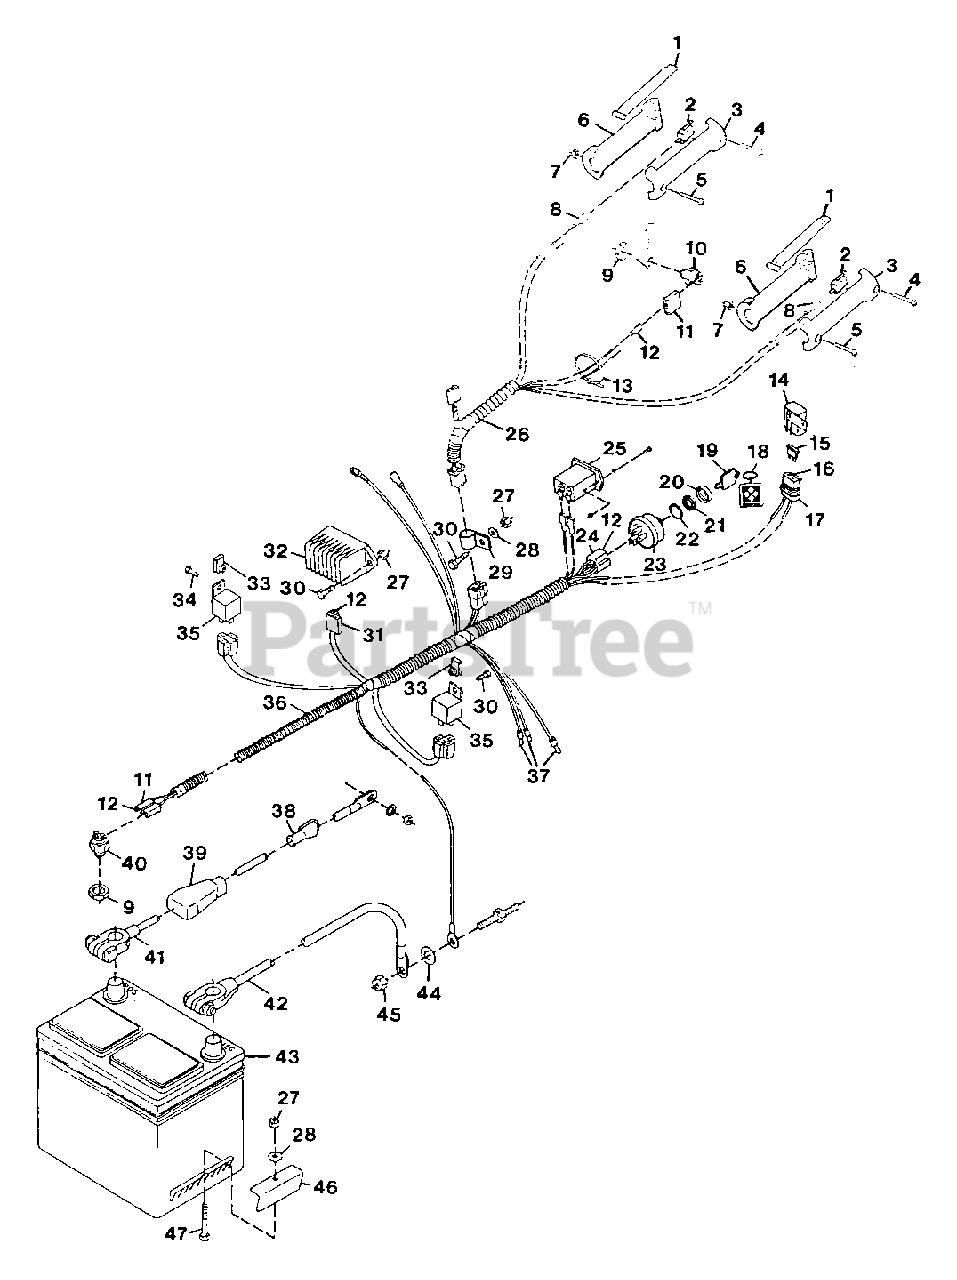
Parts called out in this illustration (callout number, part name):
1	Lever
2	Switch
3	Handle, L.H.
4	Screw, Machine 10-24x.625 PHD
5	Screw, Machine 10-24x1.50 PHD
6	Handle, R.H.
7	Nut, Lock 10-24
8	Terminal, Female
9	Nut, Stamped 9/16-18
10	Switch, Neutral Start
11	Connector, 2-Wire Switch
12	Terminal
13	Tie Wrap, Black
14	Cover
15	Fuse, 7.5 amp
16	Terminal
17	Connector
18	Chain, Key
19	Key, Ignition Switch
20	Boot
21	Nut, 9/16-24
22	Washer, Lock
23	Switch, Ignition
24	Connector
25	Hourmeter
26	Harness, Wiring Handlebar
27	Nut, Lock 1/4-20
28	Washer, Flat .281x.625x.065
29	Clamp, Nylon
30	Bolt, Hex 1/4-20x.75
31	Connector
32	Regulator, Rectifier
33	Nut, Speed 1/4-20
34	Bolt, Hex 1/4-20x.625
35	Relay
36	Harness, Wiring
37	Terminal, Male
38	Boot, Battery Cable
39	Cover, Battery Terminal
40	Switch, Interlock
41	Cable
42	Cable, Negative Battery
43	Battery, 12 Volt
44	Washer, Flat .469x.938x.065
45	Nut, Lock 3/8-16
46	Clamp
47	Bolt, Hex 1/4-20x2.00
NS	Decal, E.S. Warning French
NS	Decal
